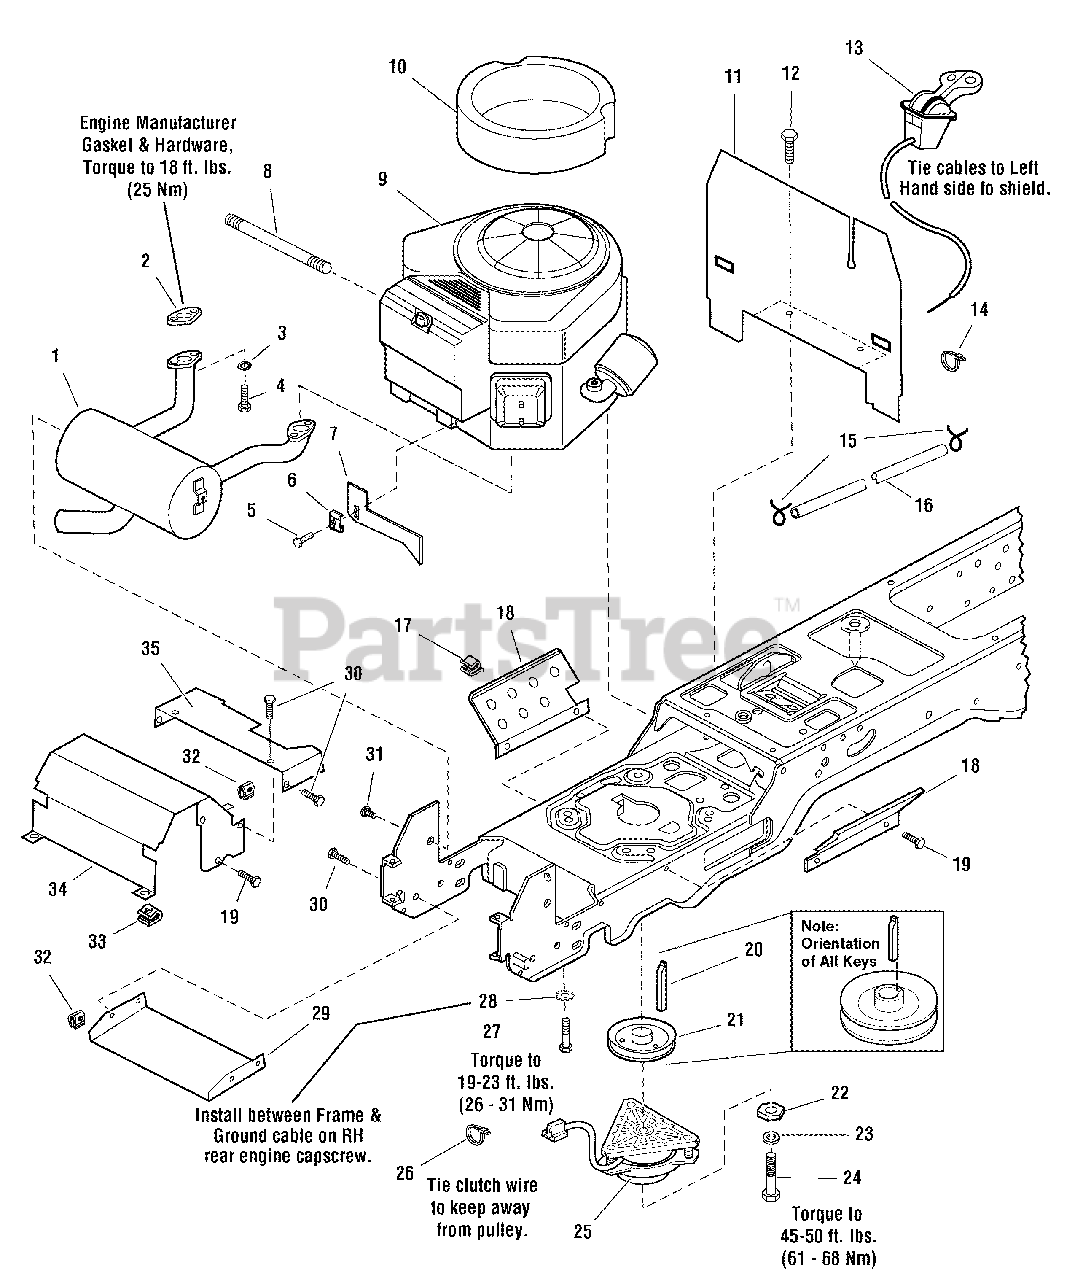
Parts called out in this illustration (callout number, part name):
1	MUFFLER
2	* GASKET
3	LOCKWASHER, 5/16
4	CAPSCREW, Socket Head, 5/16-18 x 7/8, G8
5	SCREW, Pan Head Trox, #10-32 x 5/8
6	CLAMP, Throttle Cable
7	PLATE, Limiter RPM
8	HOSE, Oil Drain
10	SEAL, Circle
11	BULKHEAD
12	CAPSCREW, Hex Head Taptite, 1/4-20 x 1/2
13	CONTROL, Throttle Double 39" Long w/Knobs
14	TIE
15	CLAMP, Hose Type E
16	HOSE, 59" Long
17	CLIP, Wire
18	SHIELD
19	SCREW, Hex Head Taptite, 1/4-20 x 3/8
20	KEY
21	PULLEY & HUB ASSEMBLY, 4-1/2 OD
22	WASHER, Hex
23	LOCKWASHER, 7/16
24	CAPSCREW, Hex Head, 7/16-20 x 2-3/4
25	CLUTCH, Electric, OGURA
26	TIE
27	CAPSCREW, Hex Head Taptite, 3/8-16 x 1-1/2
28	LOCKWASHER, External Tooth, 3/8
29	SHIELD, Muffler Bottom
30	CAPSCREW, Hex Head Flange Lock, 1/4-20 x 5/8
31	CAPSCREW, Hex Head Taptite, 5/16-18 x 1/2
32	NUT, Speed, 1/4-20
33	NUT, Speed, Lug Type, 5/16-18
34	DUCT, Muffler Top
35	DUCT, Muffler Extension
